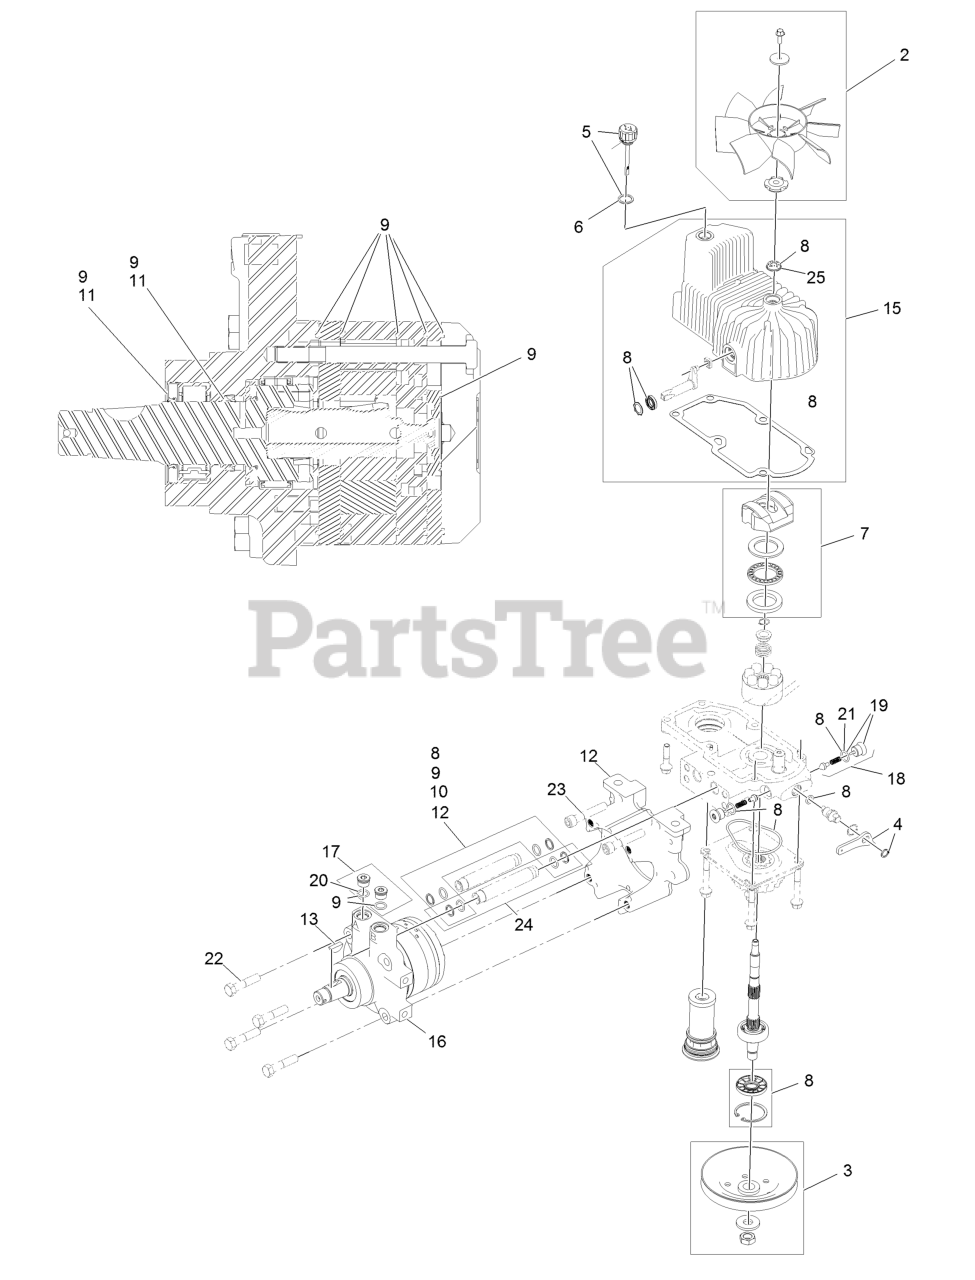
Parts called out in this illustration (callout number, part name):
2	Fan Kit
3	Pulley Kit
4	Handle-Bypass Valve, Hydro
5	Dipstick-Hydro W/Gasket
6	Gasket-Dipstick, Hydro
7	Swash Block Kit
8	Pump Seal Kit
9	Motor Seal Kit
10	Tube Seal Kit
11	Output Shaft Seal Kit
12	Nose Cup-Uht
13	Key-Woodruff 5/16 X 1
15	Housing-LH
16	Motor-Hydraulic LH 240Cc
17	Magnetic Plugs Service Kit
18	Check Valve ASM
19	Plug-Check (W/O-Ring)
21	O-Ring-Check Valve
22	Screw-HH 1/2-20 X 2 1/4
23	Screw-HSH 1/2-20 X 2 3/4
24	Hydraulic Tube Kit
25	Seal-Fan Drive
99	Flow Test Kit
99	Puller-Pulley
